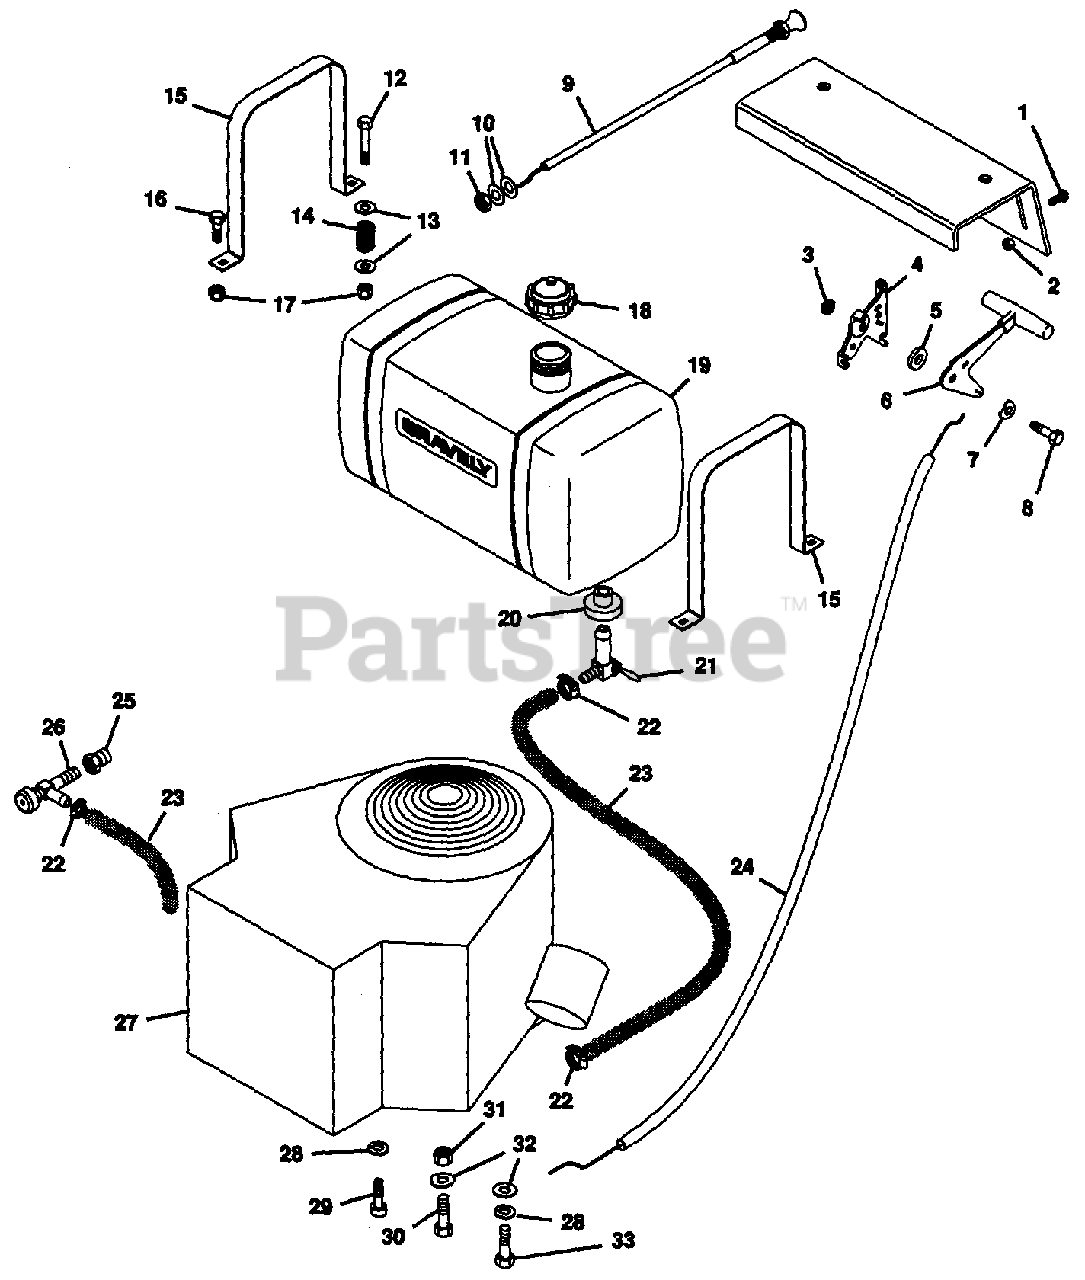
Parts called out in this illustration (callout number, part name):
1	Screw, Mach. 10-32x.50 PHD
2	Nut, Lock 10-32
3	Nut, Lock 1/4-28
4	Bracket, Mounting LH.
5	Washer, Friction
6	Assembly, Knob and Lever
7	Washer, Spring
8	Bolt, Hex 1/4-28 x .75
9	Control, Choke
10	Washer, Flat .406 x .812 x .065
11	Nut, Jam 3/8-24 Hex
12	Bolt, Hex 1/4-20 x 1.75
13	Washer, Flat .281 x .625 x .065
14	Spring, Comp. 1 x .78 x 338 Lb/in
15	Strap, Fuel Tank
16	Bolt, Hex 1/4-20 x .625
17	Nut, Lock 1/4-20
18	Cap, Fuel Tank
19	Tank, Fuel
20	Bush., Flg. .375 x 1.06 x.62 Rb.
21	Valve, Ball Shut-off
22	Clamp, Hose
23	Line , Fuel(2 feet)
24	Ass'y, Throttle Conduit(16 HP)
24	Ass'y, Throttle Conduit(17 HP)
25	Adaptor, Oil Drain(16 HP)
25	Adaptor, Oil Drain(17 HP)
26	Cock, Oil Drain
27	Engine, 16 HP B&S
27	Engine, 17 HP Kawasaki
28	Washer, Lock 5/16 Reg.
29	Screw, M8x1.25 x 2Omm SHD
30	Bolt, Hex 5/16-18 x 1.50(16 HP)
30	Bolt, Hex M8 x 1.25 30mm(17 HP)
31	Nut, Lock 5/16-18
32	Washer, Flat .344 x .688 x .065
